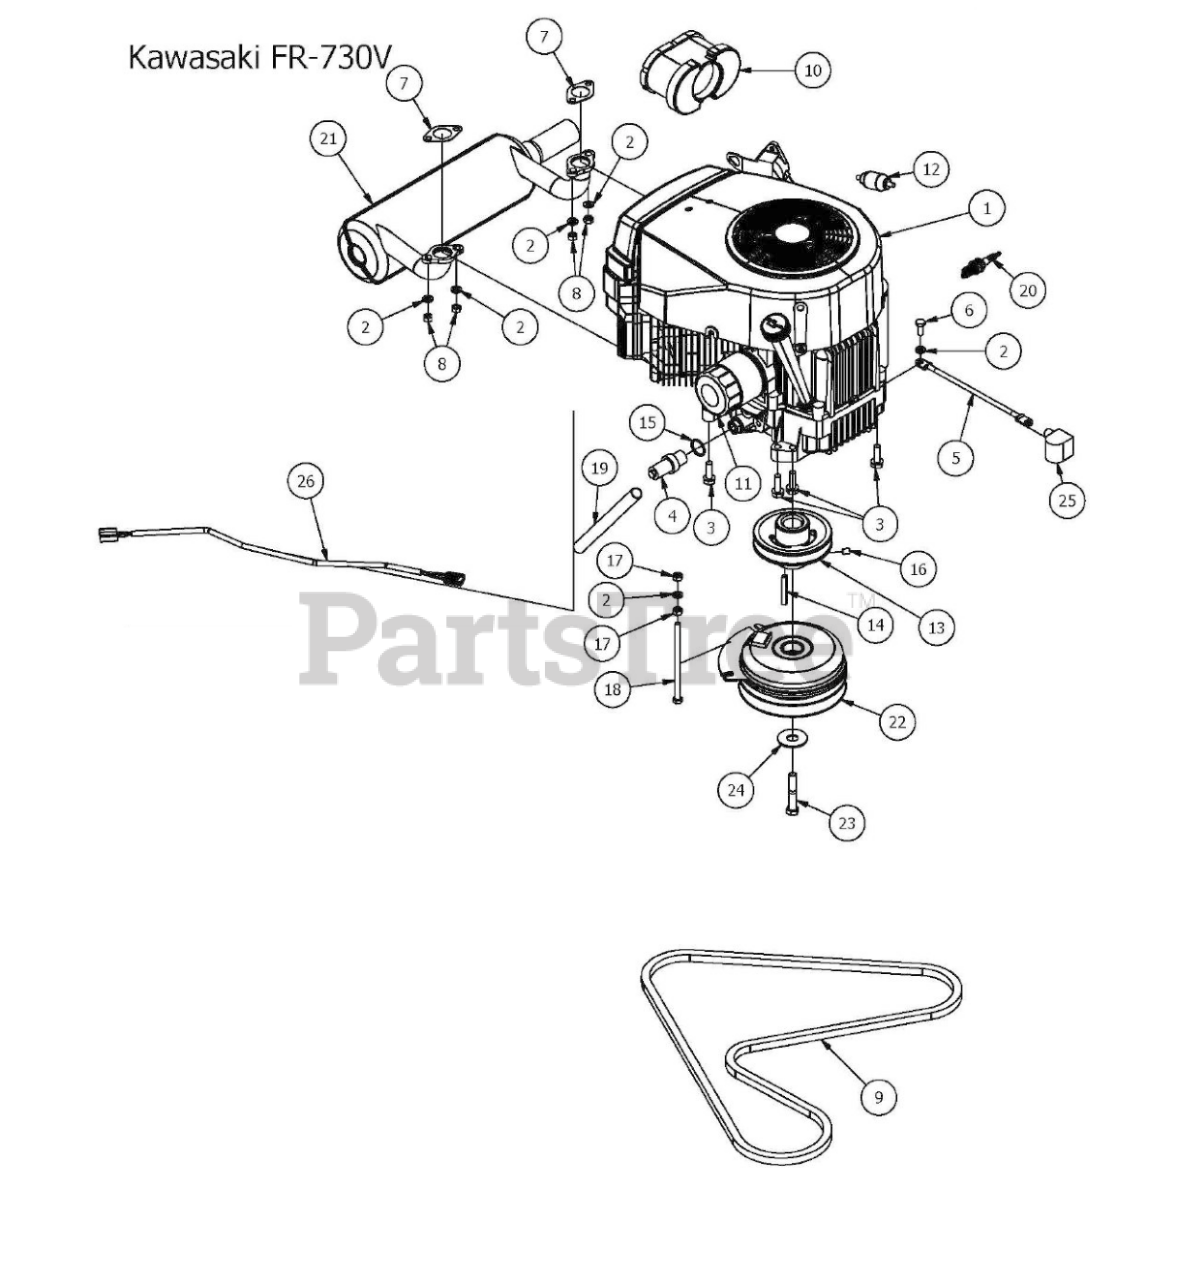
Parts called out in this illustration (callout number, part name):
1	FR730V Kawasaki Engine
2	5/16" Lock Washer
3	3/8 x 1 1/8 bolt
5	Ground Cable
6	M8x1.20x20MM Hex head bolt
7	Exhaust Gasket
8	M8-1.25 Zinc Nut
10	Kawasaki Air Filter
11	Kawasaki Oil Filter
12	Universal Inline Fuel Filter
13	4 3/4 Motor Pulley
14	1/4 x 2 Square key Stock
16	5/16 Set Screw
18	5/16-18 x 5-1/2 GR 5 Hex Bolt
19	Oil Drain Hose
20	Spark Plug- Kawasaki
21	Kawasaki Muffler 1251
22	2017 ZT Clutch Assembly
23	7/16"-20 x 2.5" Hex Bolt Gr. 8
24	Type B Plain Washer
25	Black Boot For Ground Cable
26	Clutch Pigtail
